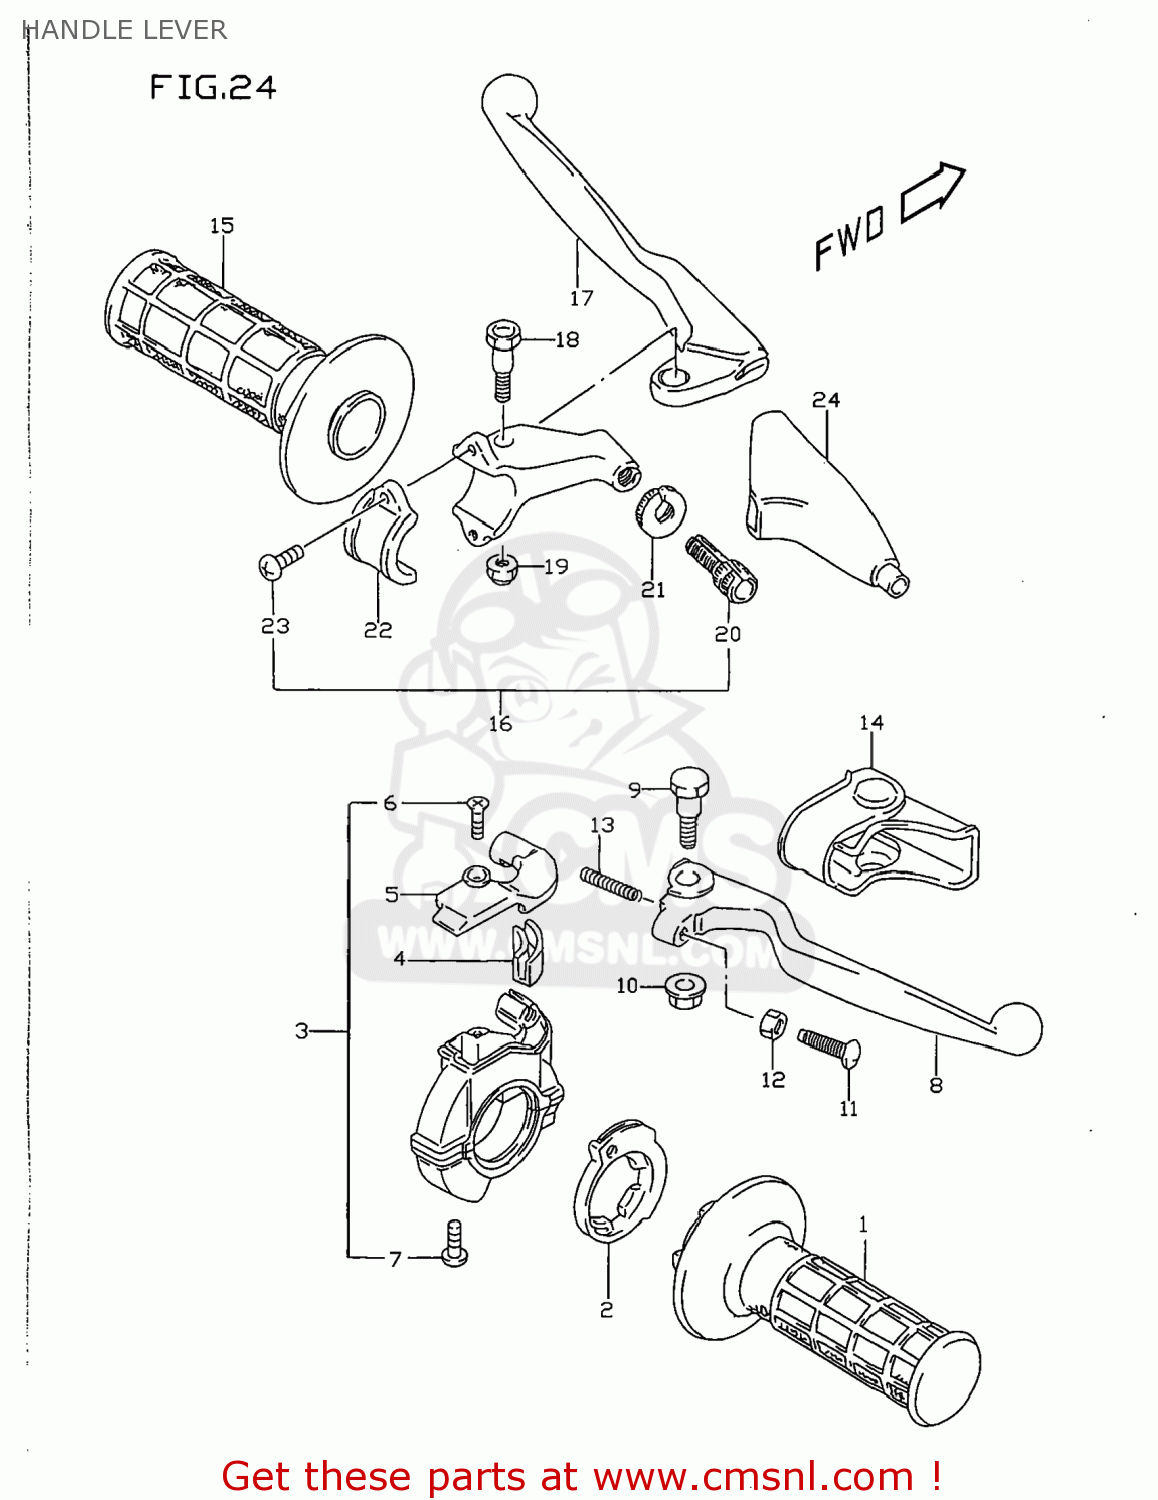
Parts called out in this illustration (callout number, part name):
1	GRIP,THROTTLE
2	ROTOR,THROTTLE GRIP
3	CASE ASSY,THROTTLE
4	GUIDE PIECE,THROTTLE
5	COVER,THROTTLE CASE
6	SCREW,UPPER
7	SCREW
8	LEVER,BRAKE
9	BOLT,BRAKE LEVER
10	NUT
11	BOLT,ADJUST
12	NUT
13	SPRING,RETURN
14	COVER,BRAKE LEVER
15	GRIP,L
16	LEVER ASSY,CLUTCH
17	LEVER,CLUTCH
18	BOLT,LEVER
19	NUT 6MM
20	ADJUSTER,CABLE
21	NUT,CABLE ADJUSTER
22	BRACKET,CLUTCH LEVER HOLDER
23	SCREW(5X14)
24	COVER,CLUTCH LEVER
